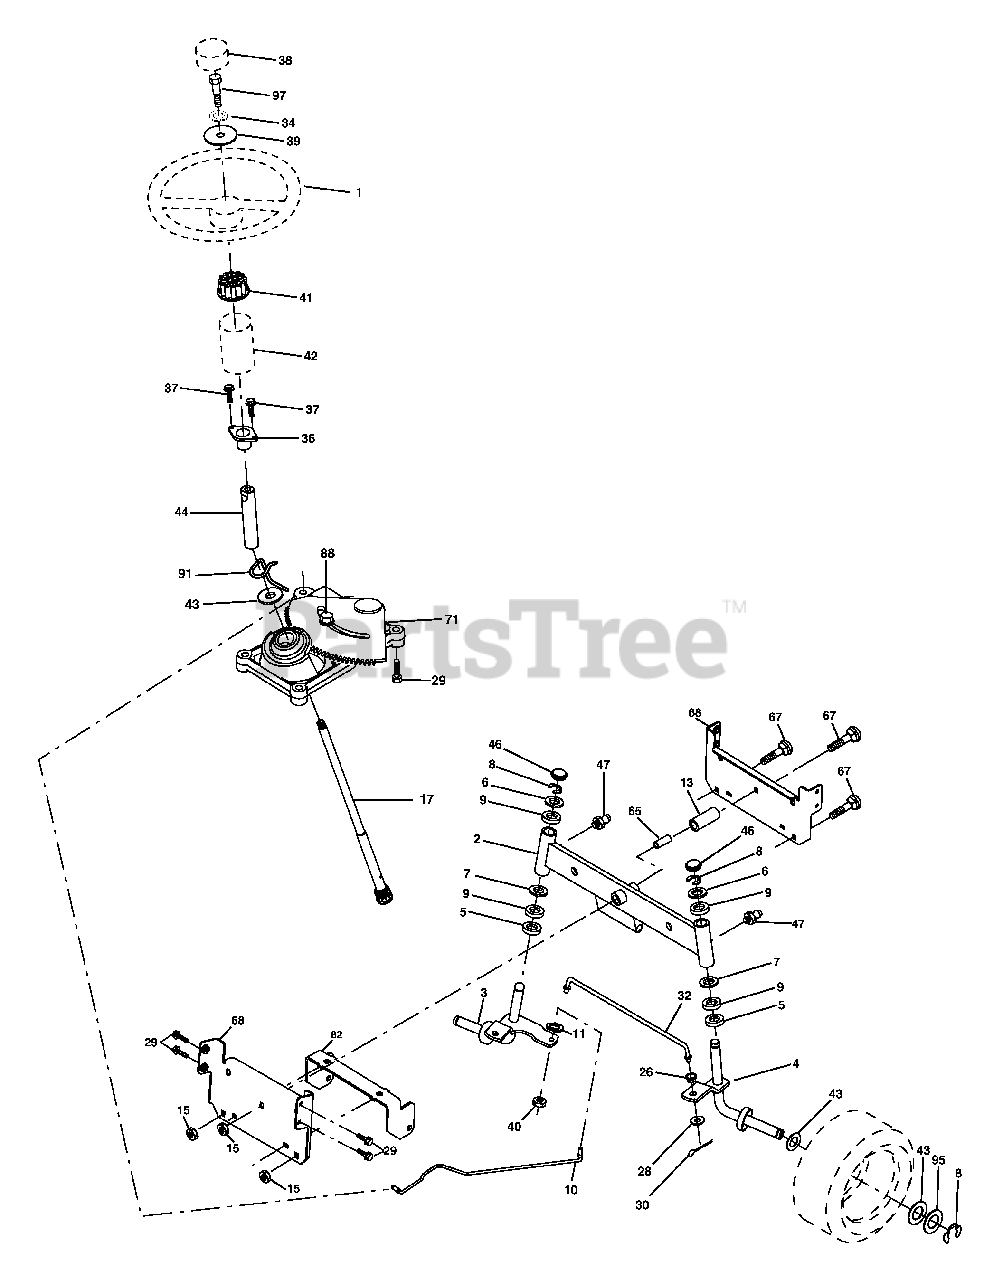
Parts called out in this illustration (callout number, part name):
1	Wheel Steering
2	Axle Asm
3	Spindle Asm LH
4	Spindle Asm RH
5	Bearing Race Thrust Harden
6	Washer 25/32 x 1-5/8 x 16 Ga.
7	Washer 27/32 x 1-1/4 x 16 Ga.
8	Ring Klip #t5304-75
9	Bearing
10	Link Drag
11	Washer Lock Hvy Hlcl Spr 3/8
13	Spacer Brg Axle Front
15	Nut Hex Flange Lock
17	Shaft Asm Steering
26	Bushing Link Drag
28	Washer 13/32 x 7/8 x 16 Ga.
29	Screw 3/8-16 x .75
30	Pin Cotter 1/8 x 3/4
32	Rod Tie
34	Washer Lock Hvy Hlcl Spr 5/16
36	Bushing Strg
37	Screw
38	Insert Cap Strg Wh
39	Washer 11/32 ID x 2-3/8 OD 12 Ga.
40	Crownlock nut
41	Adaptor Wheel Strg
42	Boot Steering Dash
43	Washer 25/32 x 1 1/4 x 16 Ga.
44	Extension Steering Shaft
46	Cap Spindle Fr Top Blk
47	Fitting Grease
65	Spacer Brace Axle
67	Bolt RDHD SQNK 3/8-16 x 2 1/4
68	Axle, Brace
71	Steering Asm
82	Bracket Susp Chassis Front
88	Bolt Shoulder 7/16-20 unc
91	Clip Steering
95	Washer Harden .739 x 1.637 x .060
97	Bolt 5/16-18 unc x 4" L Gr. 5
